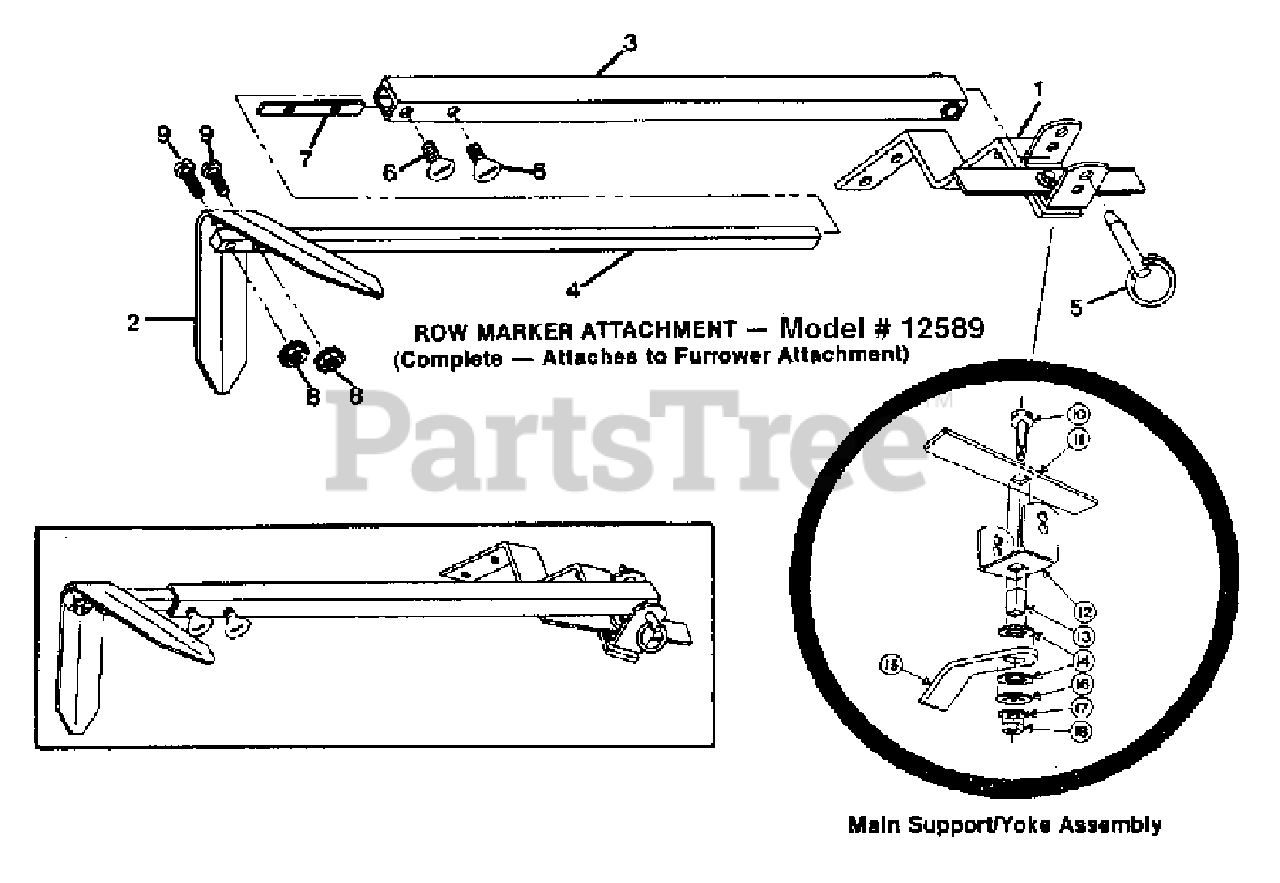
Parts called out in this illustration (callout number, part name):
1	Main support & yoke assembly, complete
2	Marker blade (blade only)
3	Marker arm, main arm
4	Marker arm, ext. arm w/stop pin
5	Hitch pin
6	Thumbscrew, 1/4-20 x 1/2
7	Nut bar
8	Nut, hex, No. 10-24 w/star washer
9	Screw, round hd., 10-24 x 1
10	Bolt, whiz lock, 3/8-16 x 1-1/2
11	Stop bar
12	Yoke
13	Tube key, square
14	Washer, friction
15	Main support
16	Washer, square hole
17	Washer, disc spring
18	Nut, hex, 3/8-16
12589	Row marker attachment, complete
